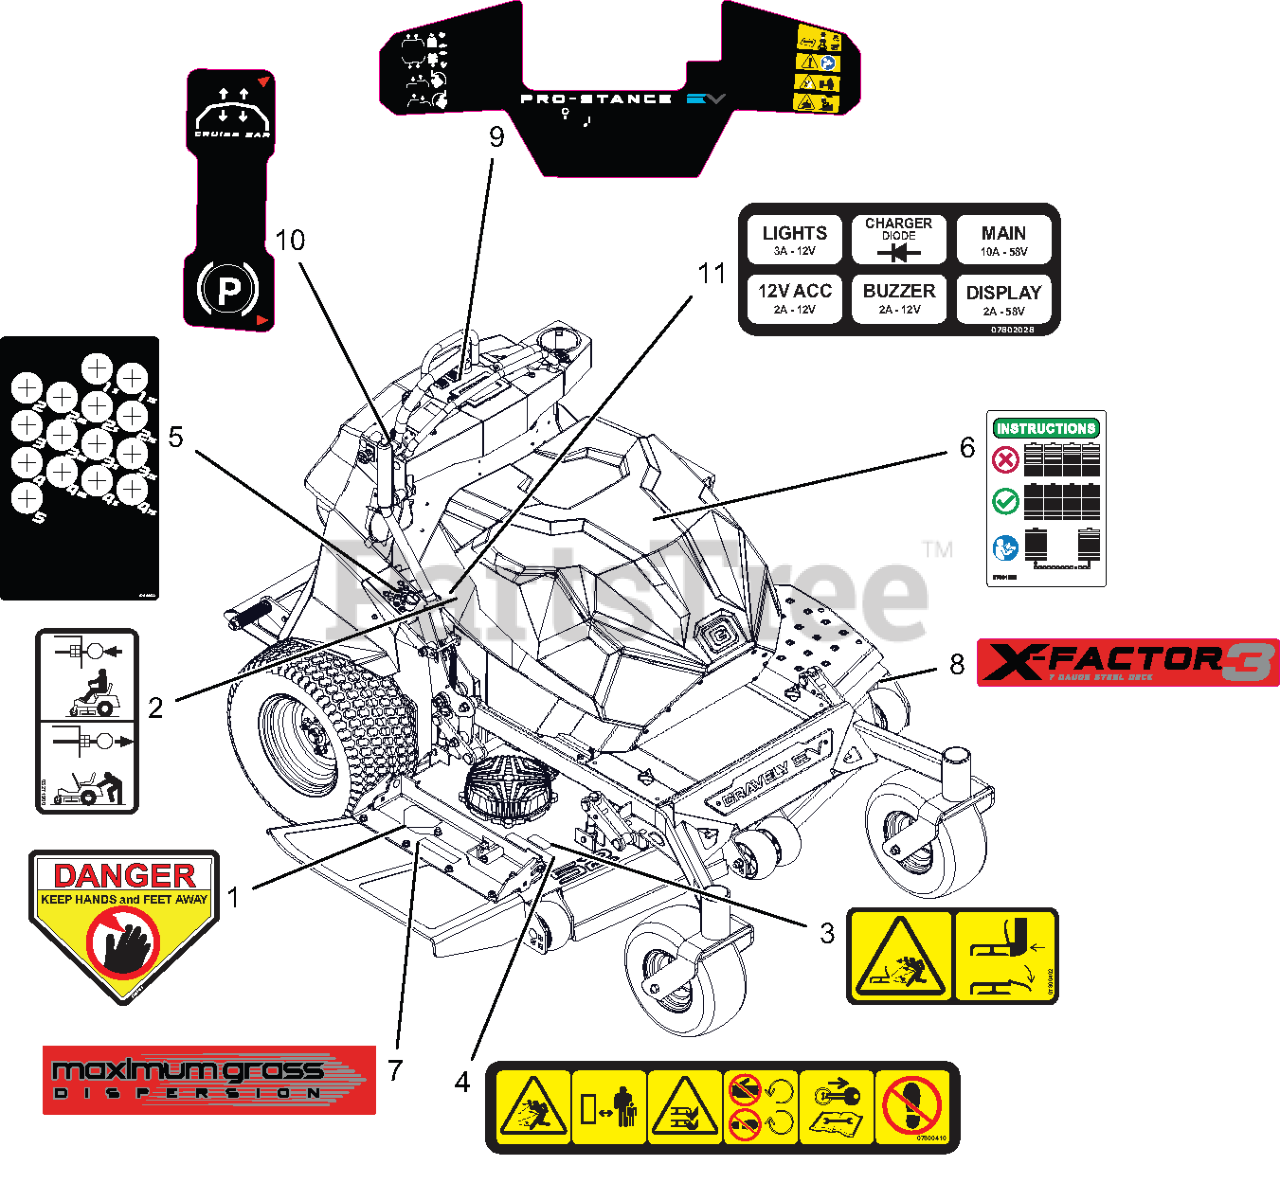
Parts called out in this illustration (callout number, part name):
1	DECAL, DANGER
2	DECAL, TRANSMISSION DISCONNECT
3	DECAL, SAFETY - DECK GUARDING
4	DECAL, DECK SAFETY
5	DECAL, DECK - HEIGHT ADJUST
6	DECAL, BATTERY BALANCE
7	DECAL, DECK - MAX GRASS
8	DECAL, DECK - X-FACTOR 3
9	DECAL- DASH PSEV MAIN
10	DECAL- DASH PSEV SECONDARY
11	DECAL, FUSE LAYOUT
